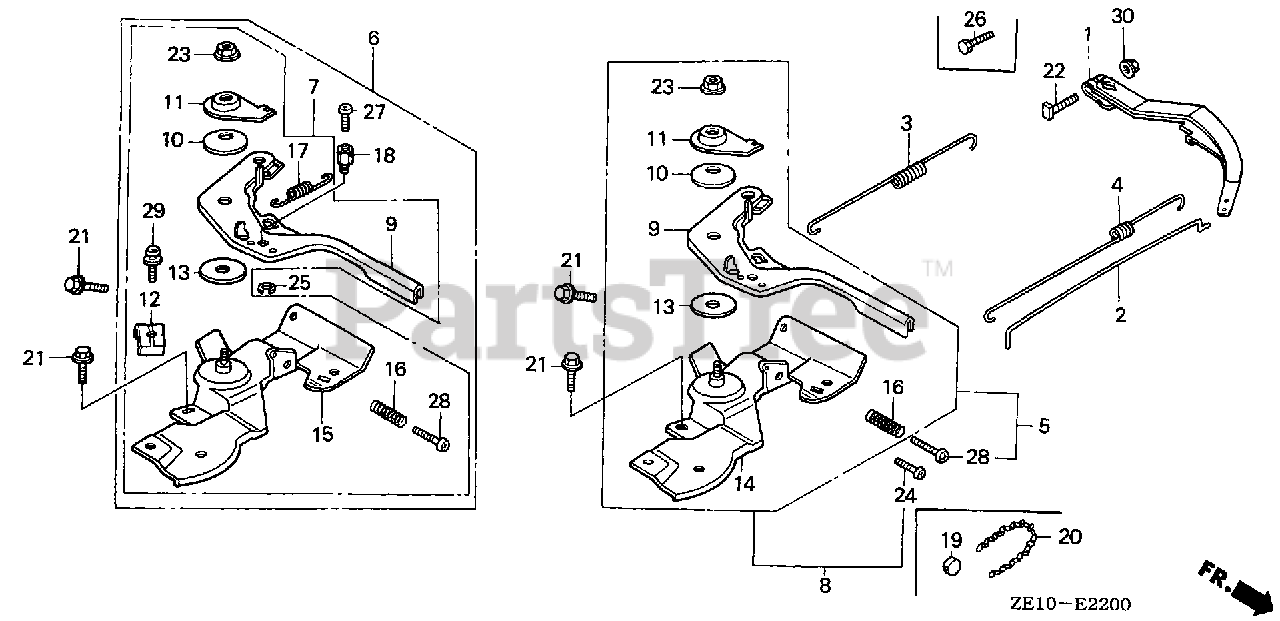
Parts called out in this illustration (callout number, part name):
1	ARM, GOVERNOR
2	ROD, GOVERNOR
3	SPRING, GOVERNOR
4	SPRING, THROTTLE RETURN
7	CONTROL ASSY. (REMOTE)
9	LEVER, CONTROL
10	SPRING, LEVER
11	WASHER, CONTROL LEVER
12	HOLDER, CABLE
13	SPACER, CONTROL LEVER
15	BASE, CONTROL (REMOTE)
16	SPRING, CONTROL ADJUSTING
17	SPRING, CABLE RETURN
21	BOLT, FLANGE (6X12) (CT200)
22	BOLT, GOVERNOR ARM
23	NUT, SELF-LOCK (6MM)
23	NUT, FLANGE (6MM)
26	BOLT, HEX. (6X20)
28	SCREW, PAN (5X20)
28	SCREW, PAN (5X25)
29	SCREW, PAN (5X16)
29	SCREW-WASHER (5X16)
30	NUT, FLANGE (6MM)
